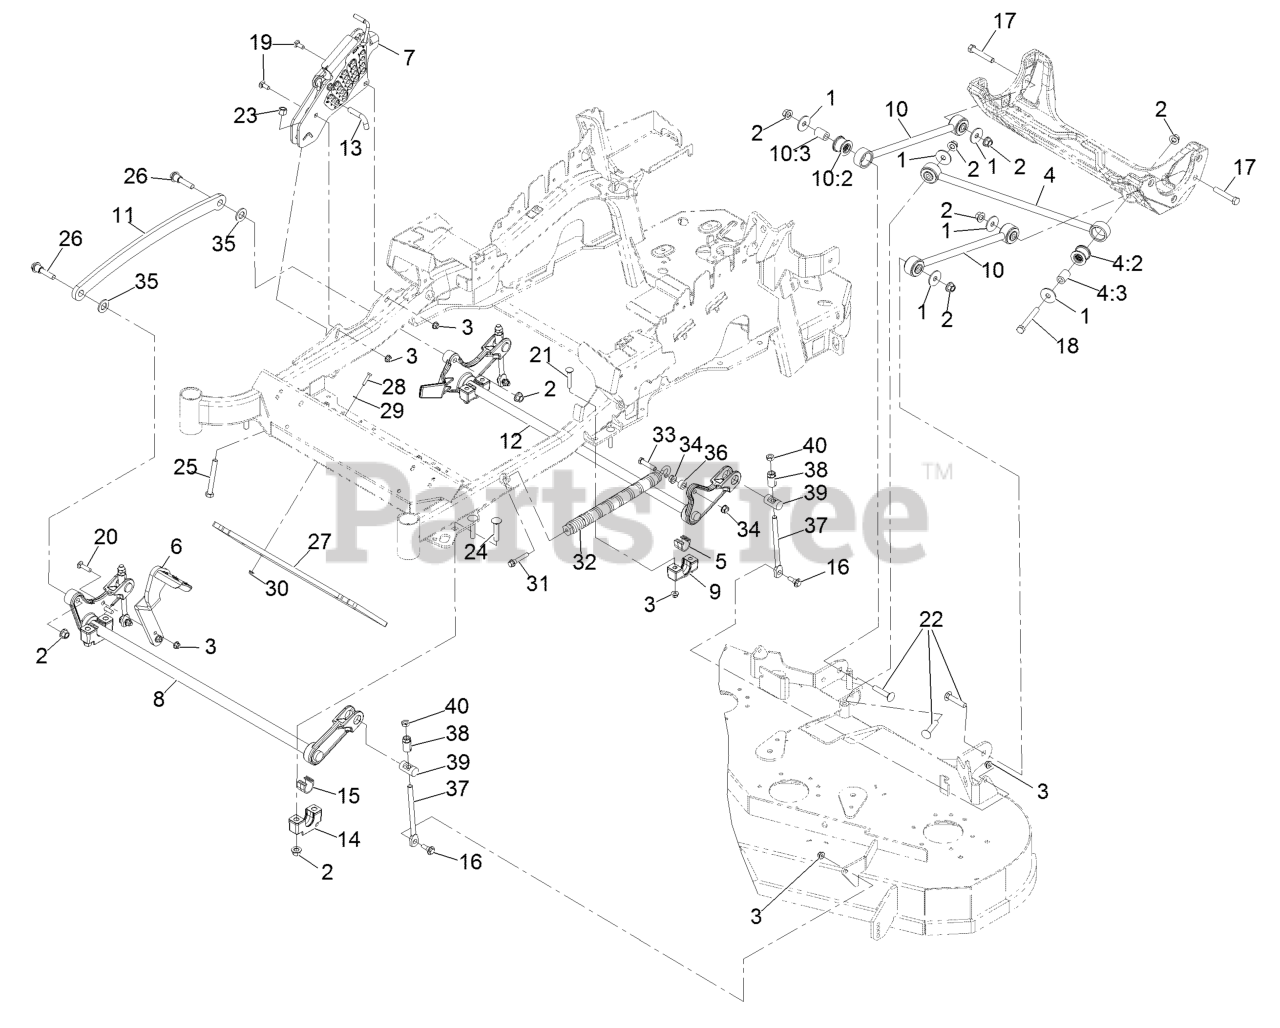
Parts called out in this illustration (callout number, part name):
1	WASHER-THRUST
2	Nut-Lock 1/2-13
3	NUT-HF, NI
4	PANHARD ROD ASM
4:2	BUSHING-SUSPENSION, RUBBER
5	BEARING-CROSS SHAFT, REAR
6	LEVER-FOOT
7	HOC ASM
8	DECKLIFT-FRONT
9	SUPPORT-CROSS SHAFT, BEARING REAR
10	DECK STRUT ASM
10:2	BUSHING-SUSPENSION, RUBBER
11	LINK-LIFT, DECK
12	LIFT-DECK, REAR
13	PIN-HOC
14	SUPPORT-CROSS SHAFT, BEARING
15	BEARING-CROSS SHAFT, FRON
16	SCREW-SHOULDER, HHF
17	SCREW-HH
18	SCREW-HH
19	BOLT-CARR
20	SCREW-CARR
21	Bolt-Carriage 3/8-16 X 2 1/4
22	SCREW-CARR
23	NUT-LOCK, NI
24	Bolt-Carriage 1/2-13 X 2 1/2 Spl Neck
25	BOLT-TAP
26	SCREW-HHF, SHOULDER
27	WEIGHT-TOE BOARD
28	SCREW-HH
29	WASHER-FLAT
31	BOLT-SHOULDER
32	SPRING-EXTENSION
33	SCREW-HH
35	WASHER-FLAT
37	LINK-ADJUSTER, DECK LIFT
38	ADJUSTER-LIFT, DECK
39	TRUNNION
40	NUT-JAM
